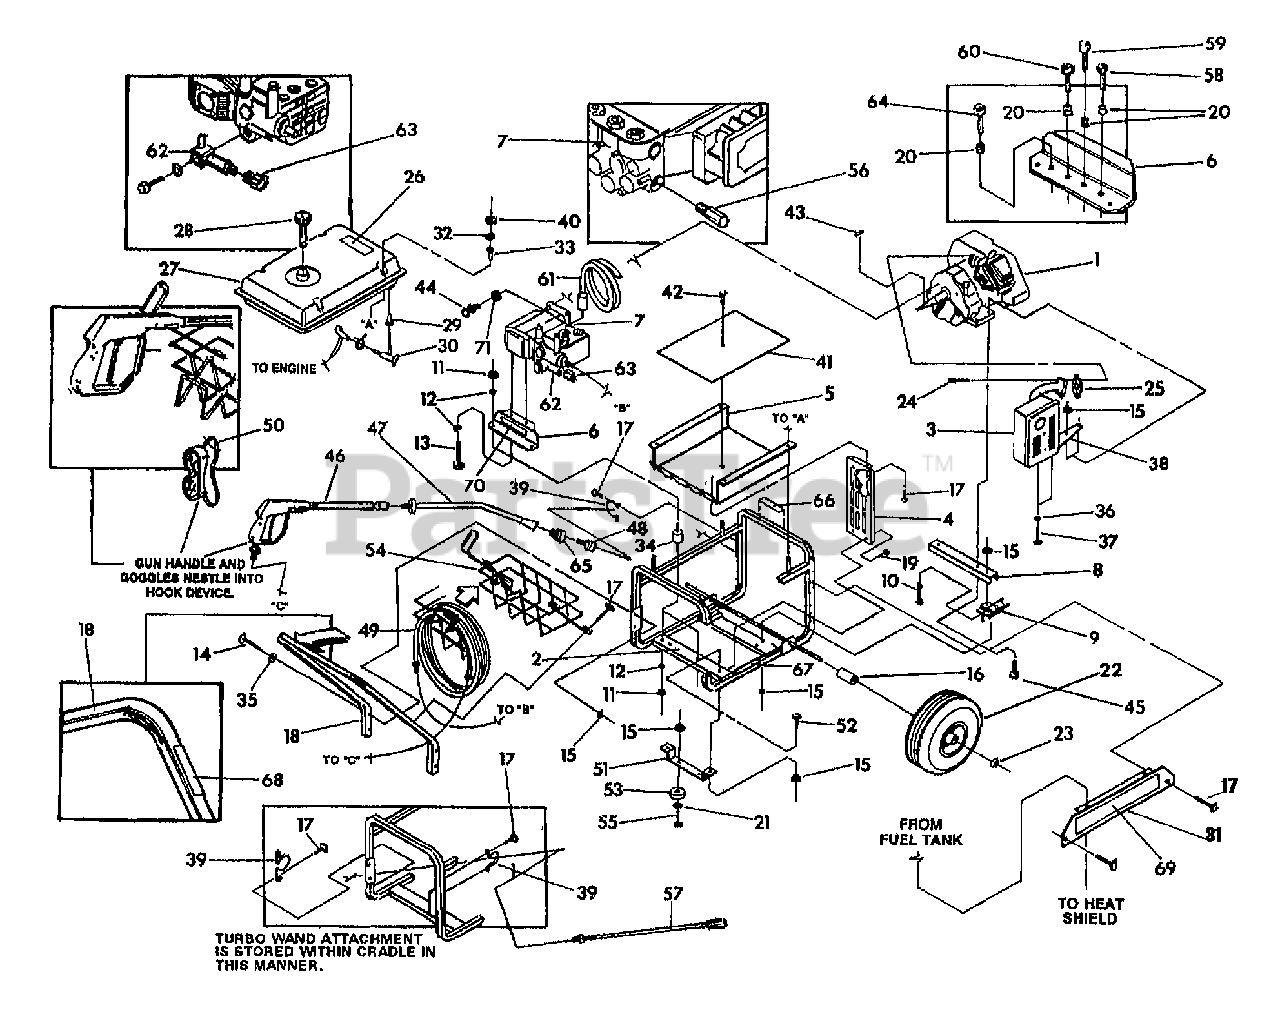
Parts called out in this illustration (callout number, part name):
1	ENGINE-GN190 (PRS WSHR)
2	FRAME-W/DECALS (PRES.WASHER)
3	MUFFLER
4	SHIELD-HEAT MUFFLER (PRS WSHR)
5	SHIELD-HEAT TANK (PRES.WASHR)
6	BRKT-PUMP MNT W/GROMMETS PRS W
7	PUMP-XTV 2200 SERIES (TB PRS W
8	SUPPORT-ENGINE
9	MOUNT-VIBRATION 45 DEG.
10	SCR M8-1.25X20MM
11	NUT-HEX M8-1.25
12	WASHER-LK M8
13	SCR-CAP M8-1.25X16MM
14	SCR-CAP M8-1.25X45MM
15	NUT-HF/LK M8-1.25
16	SPACER-WHEEL (PRS WSHR)
17	SCR-CAP M10-16 SELF DRILL
18	HANDLE-GUIDE (PRES.WSHR)
19	SCR-M8X.75 TAPTITE
20	GROMMET-NOZZLE (PRS WSHR)
21	WASHER-M8 VIBRATION MOUNT
22	ASSM-WHEEL (PRES.WSHR)
23	NUT-LK 5/8-11 W/NYLON INSERT
24	SCR-SKT HD M8-1.25X20 LONG (GE
25	GASKET-EXHAUST
26	DECAL-START INST (PRS WSHR)
27	TANK-FUEL
28	GAUGE-FUEL
29	BUSHING-PLASTIC TANK (PRS WSHR
30	VALVE-FUEL TANK (PRES.WSHR)
31	PANEL-SIDE DECAL
32	WASHER-SPECIAL BLACK (PRS WSHR
33	GROMMET-TANK
34	MOUNT-SHOCK
35	WASHER-M8X25MM
36	WASHER-LK M6
37	SCR-CAP M6-1.0X12MM
38	BRACKET-MUFFLER
39	HOLDER-REAR GUN
40	NUT-HF/LK M6 FLANGE
41	INSULATION-1/4" THICK #2
42	CLIP-INSULATION
43	KEY-.188 SQ X .25
44	SCR 5/16-24X.75 W/LK WSHR
45	SCR-PHP M8X35MM
46	GUN-MASTER CONTRACTOR
47	EXTENSION-WAND M.C.
48	NOZZLE-CHEMICAL INJECTOR
49	ASSM-HOSE 3/8" ID (50FT)
50	GOGGLES
51	BRKT-UNIT SUPT (TB PRS WSHR)
52	SCR-HH M8-1.25X20MM
53	MOUNT-VIBRATION
54	BASKET-WIRE (PRES.WASHER)
55	SCR-HH M8-1.25X30MM
56	VALVE-THERMAL RELIEF (PRS WSHR
57	UD ASSM-TURBO WAND
58	NOZZLE-QUICK CON 00045 RED
59	NOZZLE-QUICK CON 15045 YELLOW
60	NOZZLE-QUICK CON 25045 GREEN
61	ASSM-FILTER&INJECTOR TUBE
62	NECK-ALUMINUM PUMP (PRS WSHR)
63	CONNECTOR-(BRASS) GARDEN HOSE
64	NOZZLE-QUICK CON 40045 WHITE
65	ADAPTOR-QUICK CONNECT (PRS WSH
66	WASHER-LK M8
67	DECAL-WARNING HOT SURFACE
68	DECAL-CAUTION SPRAYGUN (PRS WS
69	DECAL-TROY/BILT LOGO
70	DECAL-NOZZLE (PRS WSHR)
71	KIT-SVC ENG 8HP STD C/V I
